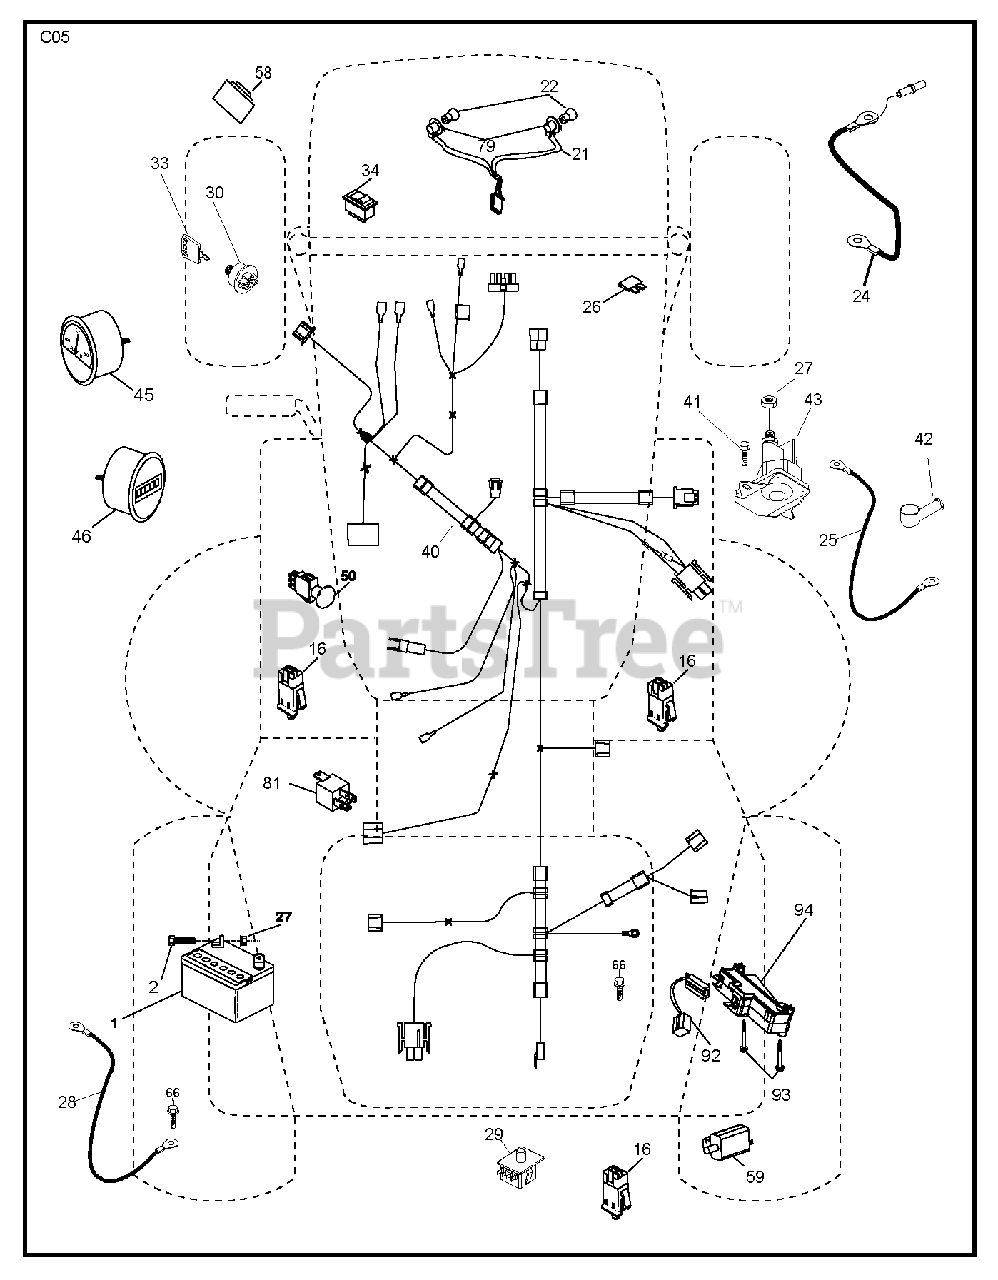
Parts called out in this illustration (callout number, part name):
1	REPL BY 532 12 38-99
16	SWITCH INTERLOOK PUSH-IN
21	HARNESS.W/LIGHT SOCKET
22	LIGHTBULB
24	CABLE BATTERY 6 GA. 11" RED
26	FUSE 20AMP
27	NUT
28	CABLE GROUND
29	SWITCH.SEAT.DP W/RAMPS
30	SWITCH.IGN.DELTA.W.LGH.ROS
33	KEY.CHAIN.BLISTER.PACK.GEN.INT
34	SWITCH LT
42	TERMINAL COVER
43	SOLENOID.W/BRASS.PLUNG
50	PTO SWITCH
58	BUZZER
79	BULB HOLDER ASM.
81	RELAY.ASSY.T
92	HARNESS.PIGTAIL.CONSLE
93	SCREW.PLASTITE
94	MODULE.REVERSE.ROS
